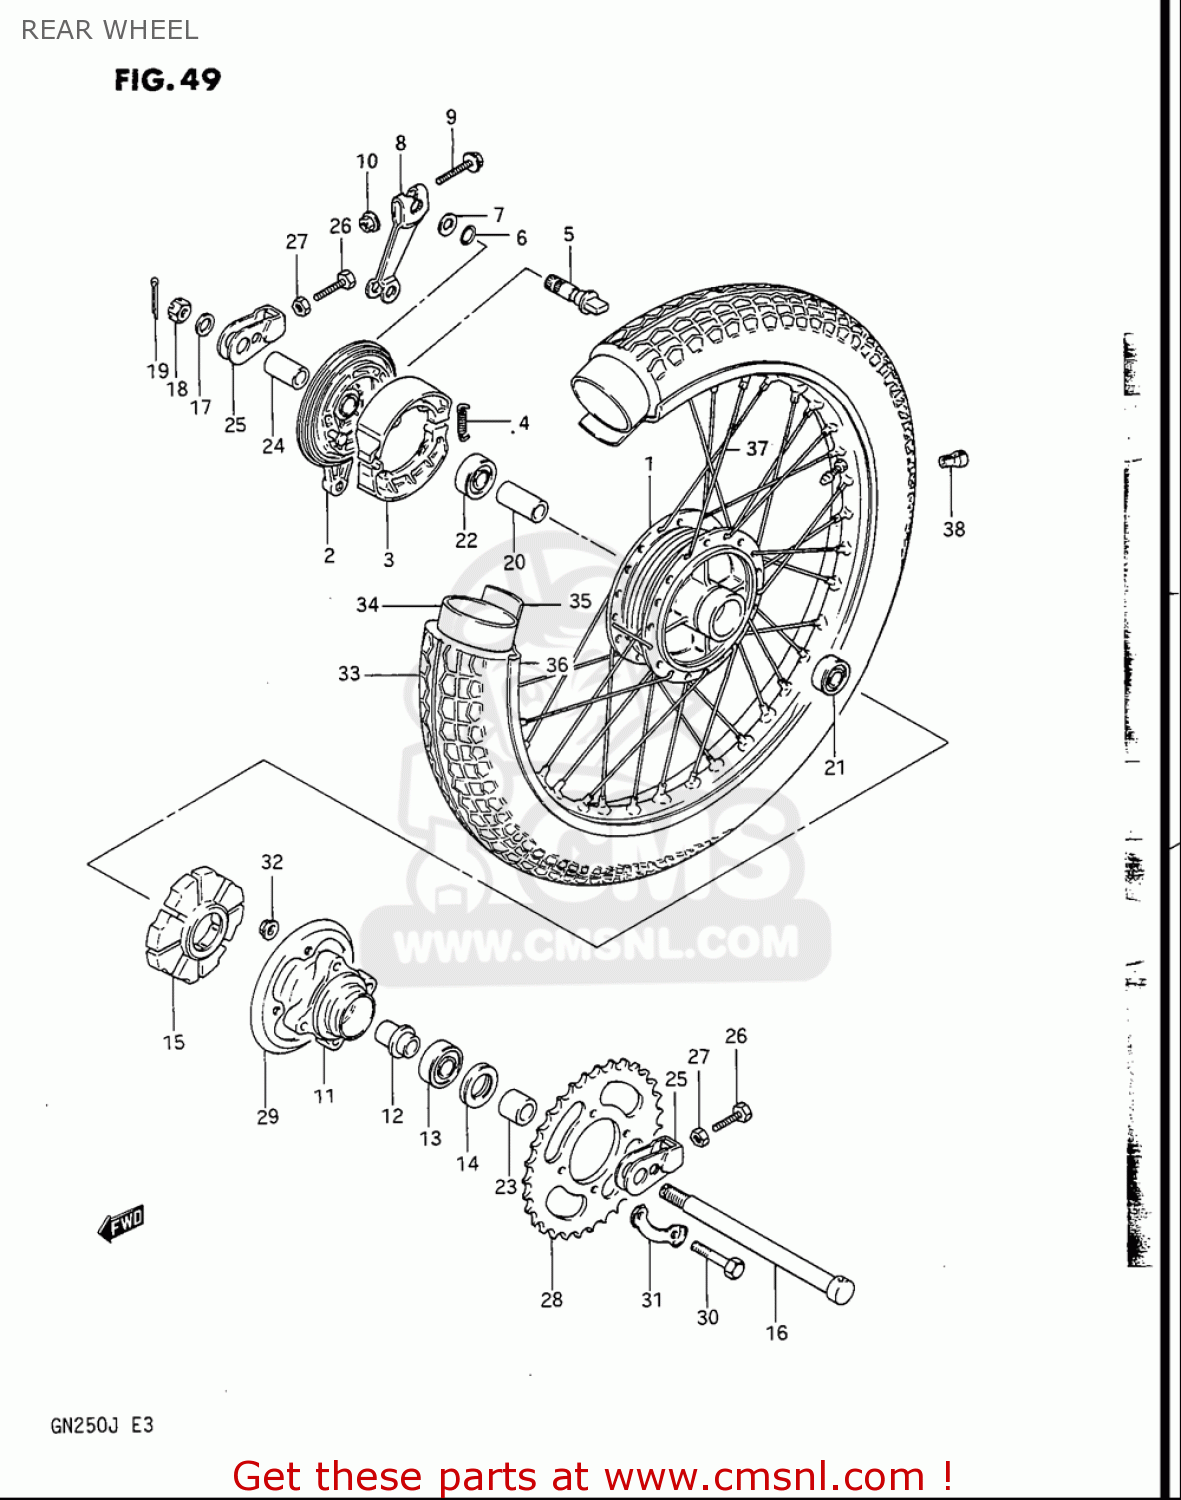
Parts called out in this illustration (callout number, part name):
1	HUB,RR
2	PANEL,RR BRAKE ANCHOR
3	SHOE SET,BRAKE (NAS)
4	SPRING(L:35.8)
5	CAM,BRAKE
6	O RING(D:2.5,ID:13.8)
7	WASHER(14.5X22X1.6)
8	LEVER,RR BRAKE CAM
9	BOLT
10	NUT
11	DRUM,RR SPROCKET MOUNTING
12	RETAINER,RR SPROCKET DRUM
13	BEARING(20X47X14)
14	SEAL,OIL(28X47X7)
15	ABSORBER ASSY,HUB SHOCK
16	AXLE,REAR
17	WASHER
18	NUT
19	PIN
20	SPACER(15.3X21.7X63)
21	BEARING
22	BEARING
25	ADJUSTER,CHAIN
26	BOLT 8X50
27	NUT
28	SPROCKET,RR(NT:41-520)
30	BOLT(10X40)
31	WASHER
32	NUT
33	TIRE,RR
34	TUBE ASSY,WHEEL,INNER 4.60-16
35	PROTECTOR,WHL INR TUBE
36	RIM,RR WHEEL(215X16)
37	SPOKE ASSY,RR WHEEL
38	BALANCER,WHEEL (B)
